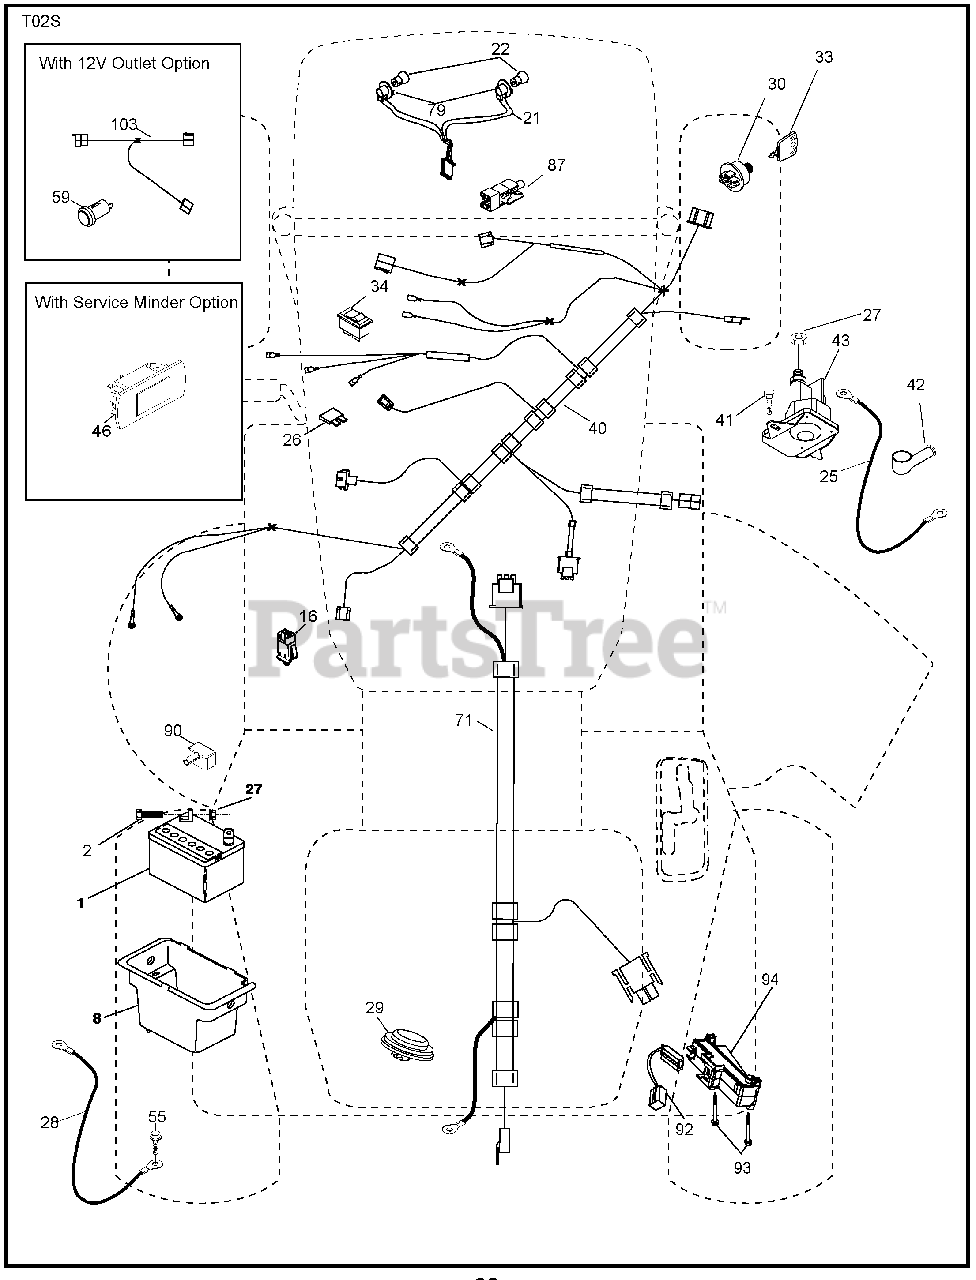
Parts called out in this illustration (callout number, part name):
1	Battery
2	Bolt Hex Head 1/4-20 x 3/4
8	Box Battery
16	Switch Interlock Push-In
21	Harness Socket Light w/4152J
22	Bulb Light
25	Cable Starter
27	Nut Keps Hex 1/4-20 unc
28	Cable, Ground
29	Switch, Seat
30	Switch, Ign
34	Switch Light/Reset
40	Harness Ign. Dash
41	Screw Thd Cut 1/4-20 x 1/2
42	Cover, Terminal
43	Solenoid
55	Screw Thdrol 5/16-18 x 3/4
71	Harness Chassis
79	Socket Asm Bulb Twistlock
87	Switch Interlock Clutch Cable
90	Cover, Terminal Battery
92	Harness Pigtail Reverse Switch
93	Screw Plastite 10-14 x 2.0
94	Module Reverse ROS
